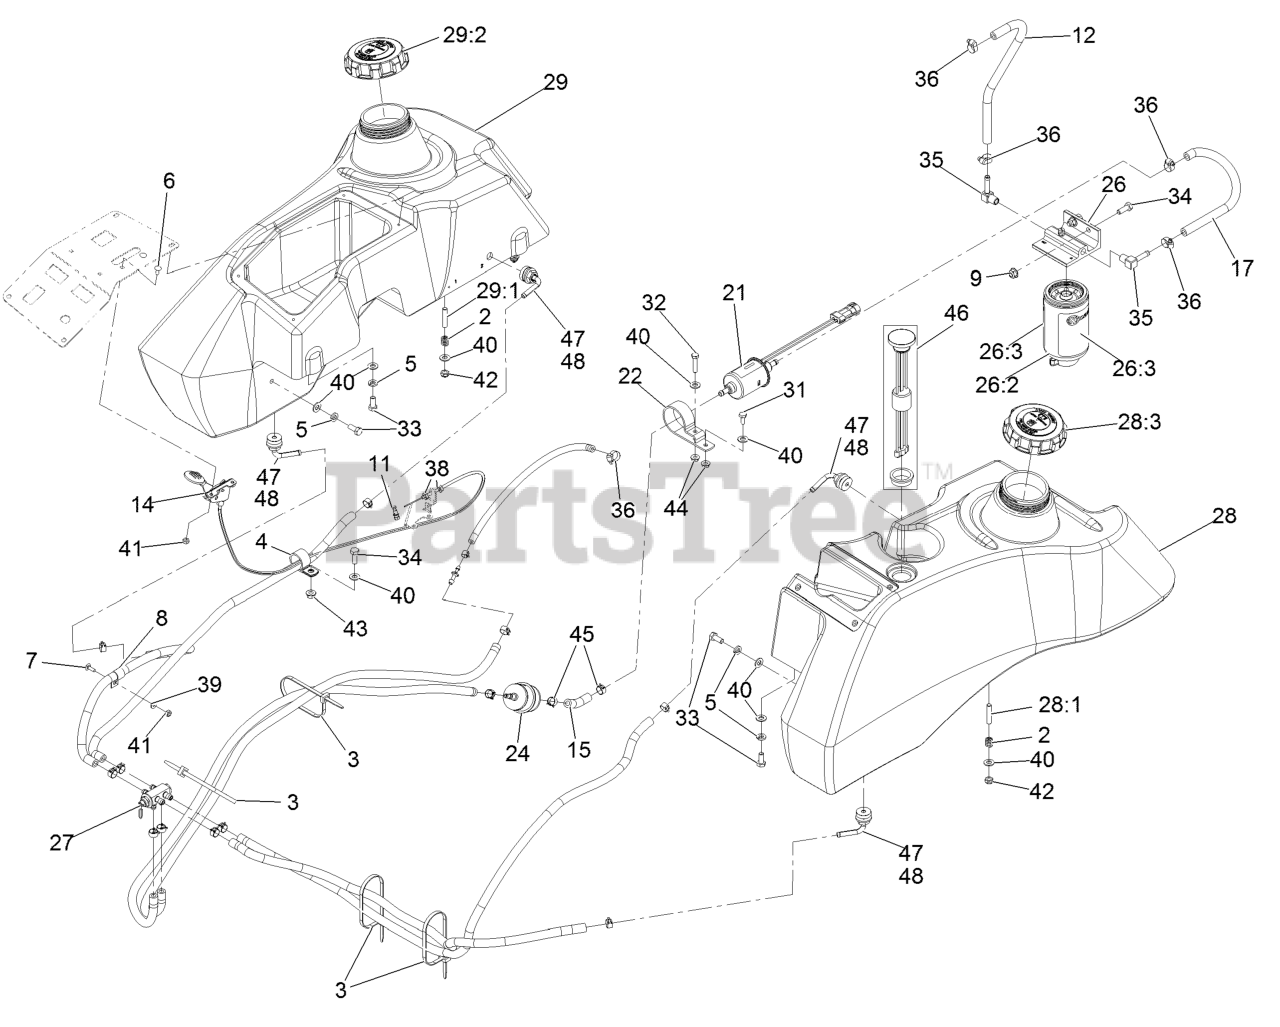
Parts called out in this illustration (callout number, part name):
2	SPRING-TANK, FUEL
3	TIE-PLASTIC
4	CLIP-LOOM
5	WASHER-LOCK
6	BOLT-CARR
7	BOLT-CARR
8	CLIP-HALF, LOOM
9	NUT-HF, NI
11	SWIVEL-STOP, CABLE
12	HOSE-FUEL
14	CABLE,THROTTLE
15	HOSE-FUEL
17	HOSE-FUEL
21	PUMP-FUEL
22	BRACKET-PUMP, FUEL
24	FILTER-INLINE
26	FUEL FILTER ASM
26:2	FILTER-FUEL
26:3	Decal,Exmark Filter
27	ASM, Fuel Valve-Hoses
28	ASM,FUEL TANK LXS LH
28:1	STUD
28:3	CAP-BIODIESEL
29	ASM, FUEL TANK LXS RH
29:1	STUD
29:2	CAP-BIODIESEL
31	SCREW-HH
32	SCREW-HH
33	SCREW-HH
34	SCREW-HH
35	FITTING-HYD, 90 DEG
36	CLAMP-WORM
38	NUT-JAM
39	WASHER-FLAT
40	WASHER-PLAIN
41	NUT-LOCK, NI
42	NUT-LOCK, NI
45	CLAMP-HOSE
46	KIT, CT FUEL GAGE REPL.
47	FITTING,FUEL BULKHEAD W/O
48	O-RING,BULKHEAD FITTING
